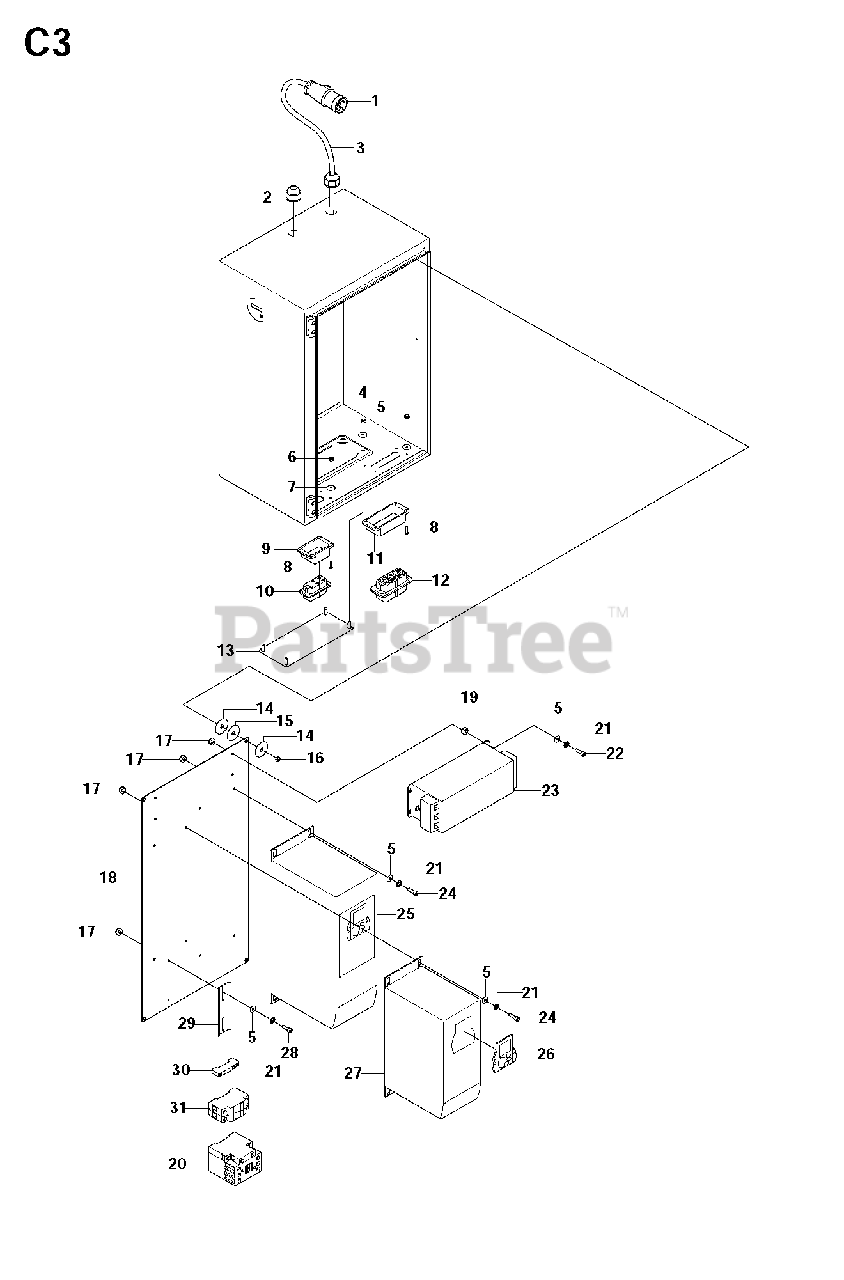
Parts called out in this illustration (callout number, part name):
2	GROMMET32AMP 5 PIN MALE PLUG
4	HEXAGON LOCKING NUT63AMP 4 PIN MALE PLUG
5	WASHERJPN/USA (200V)
6	HEXAGON LOCKING NUT
16	HEXAGON LOCKING NUT
